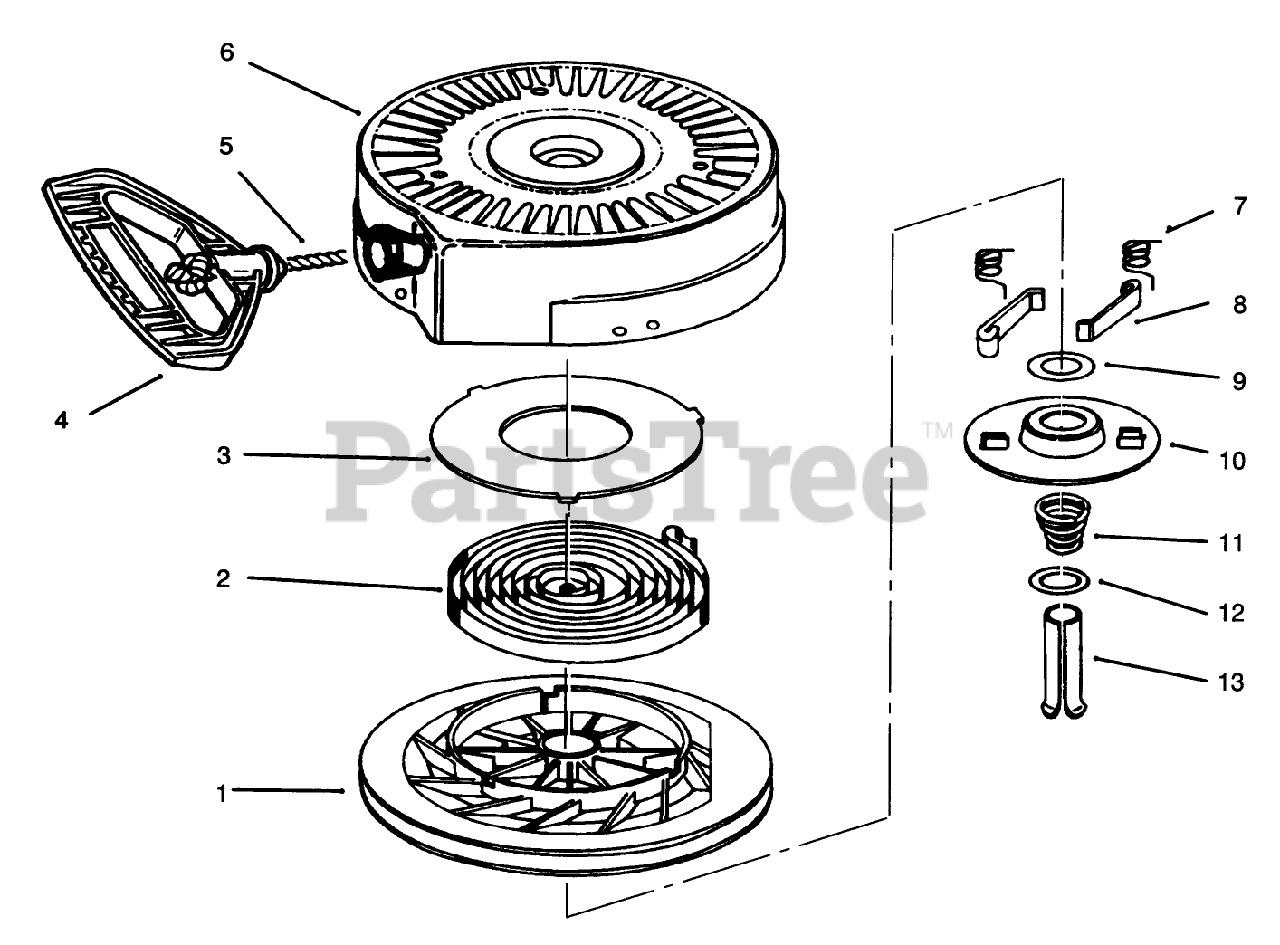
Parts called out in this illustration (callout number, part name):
1	Pulley and Rewind Spring ASM
2	Rewind Spring
3	Cover-Spring
4	Handle-Starter, Mitten Grip
5	Rope-Starter (98 cut to length)
6	Housing Assembly
7	Spring-Dog
8	Dog-Starter
9	Brake Spring
10	Washer
11	Retainer
12	Washer
13	Pin, Spring (Incl. Ref. #7)
